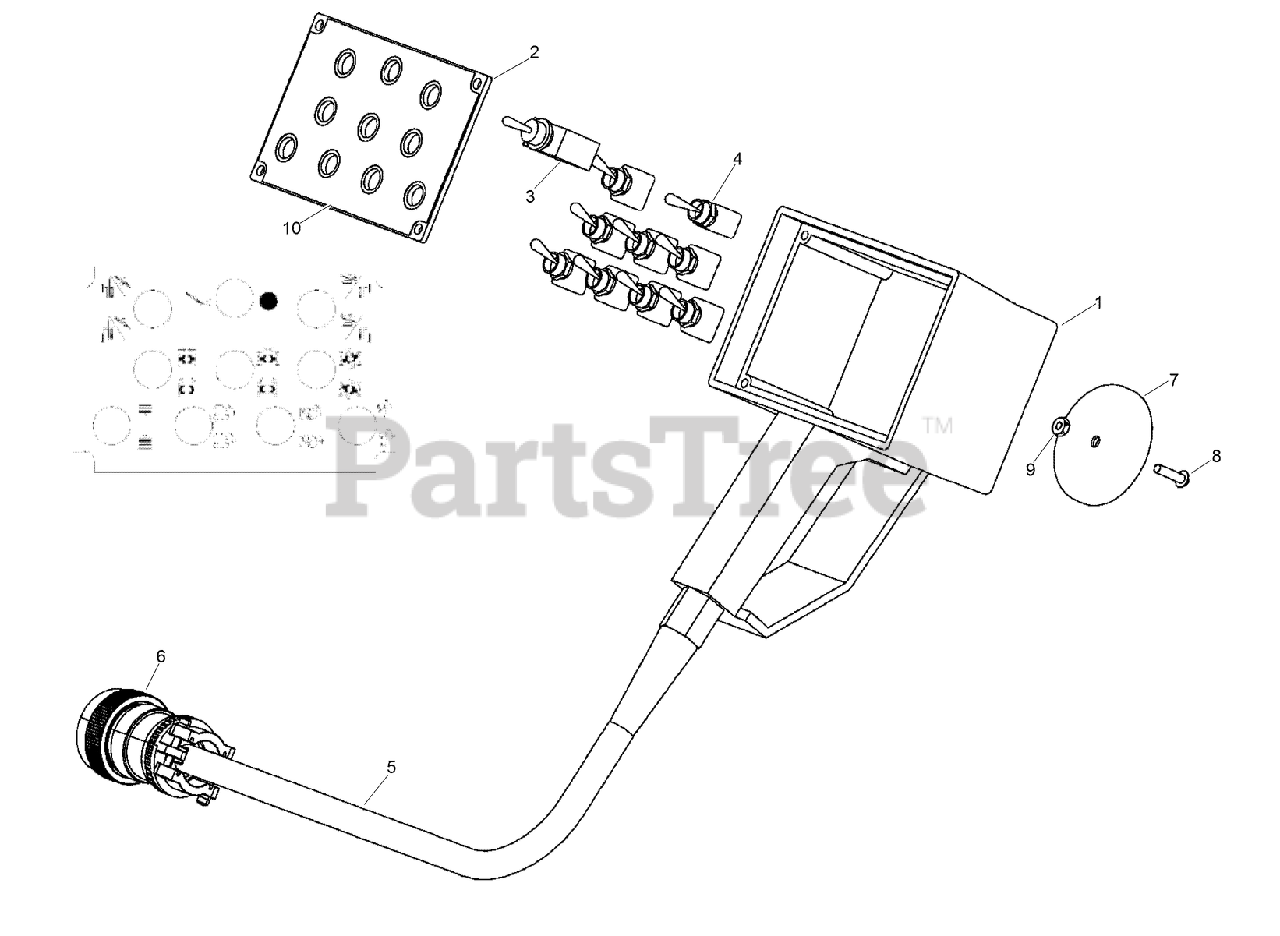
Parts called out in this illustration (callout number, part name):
1	ENCLOSURE - Handheld Device
2	PLATE - Mounting, Life Jacket
3	SWITCH - Toggle, SPDT
4	SWITCH - Toggle, Mini, (On)-Off-(On)
5	CORD - Control, Retractable, 24 / 10
6	CONNECTOR - Electrical, Deutsch HD36-24
7	MAGNET - Ceramic, 2.03 Diameter x .312 H
8	SCREW - Machine, 10 - 32 x 3/4 Slotted Pan Head
9	NUT - Hex, #10-32 UNF, 303 Stainless Steel
10	DECAL - Life Jacket Device
